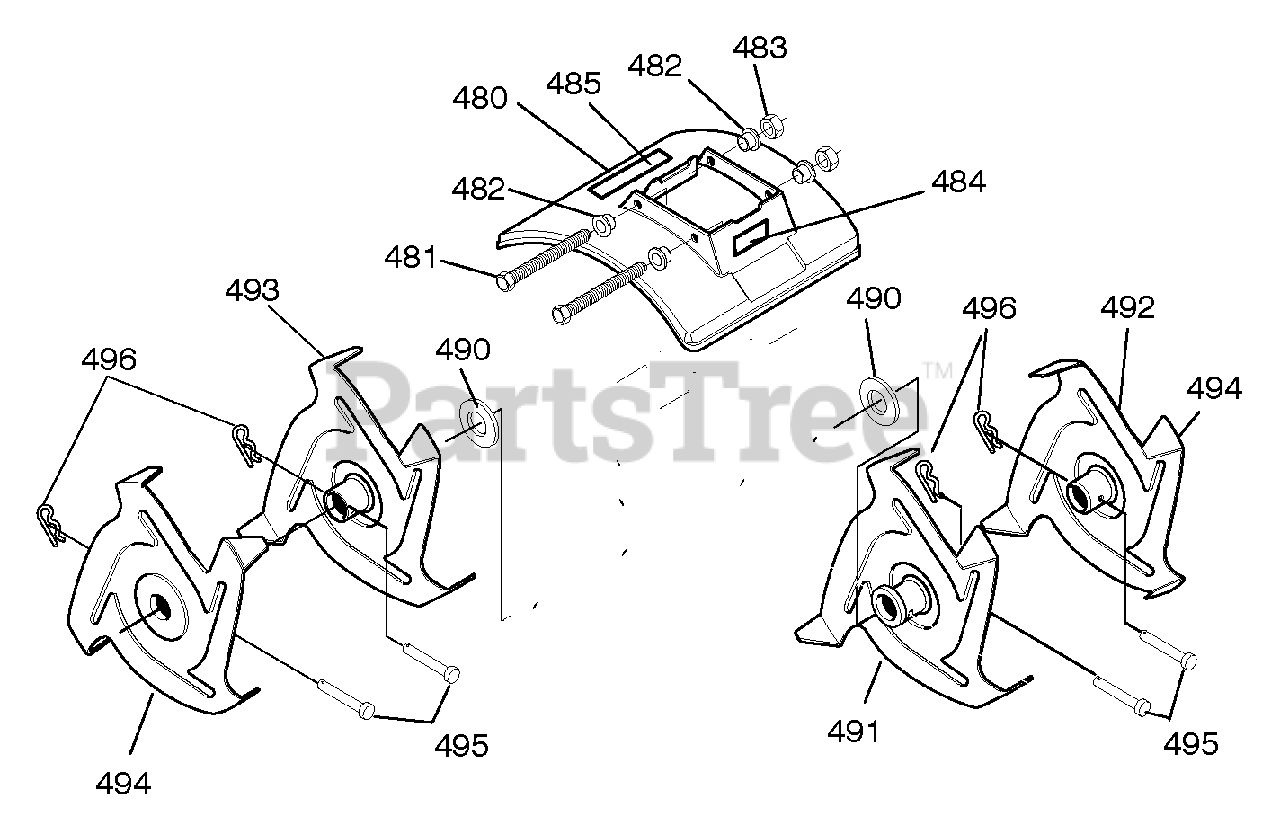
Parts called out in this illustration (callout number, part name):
480	Shield, Tine
481	Screw, 1/4-20x5.50
482	Spacer, Flange
483	Nut, 1/4-20
484	Decal, Murray
485	Decal, Caution
490	Washer, Felt
491	Tine Assy. Inner LH
492	Tine Assy. Outer LH
493	Tine Assy. Inner RH
494	Tine Assy. Outer RH
495	Clevis Pin
496	Hair Pin
